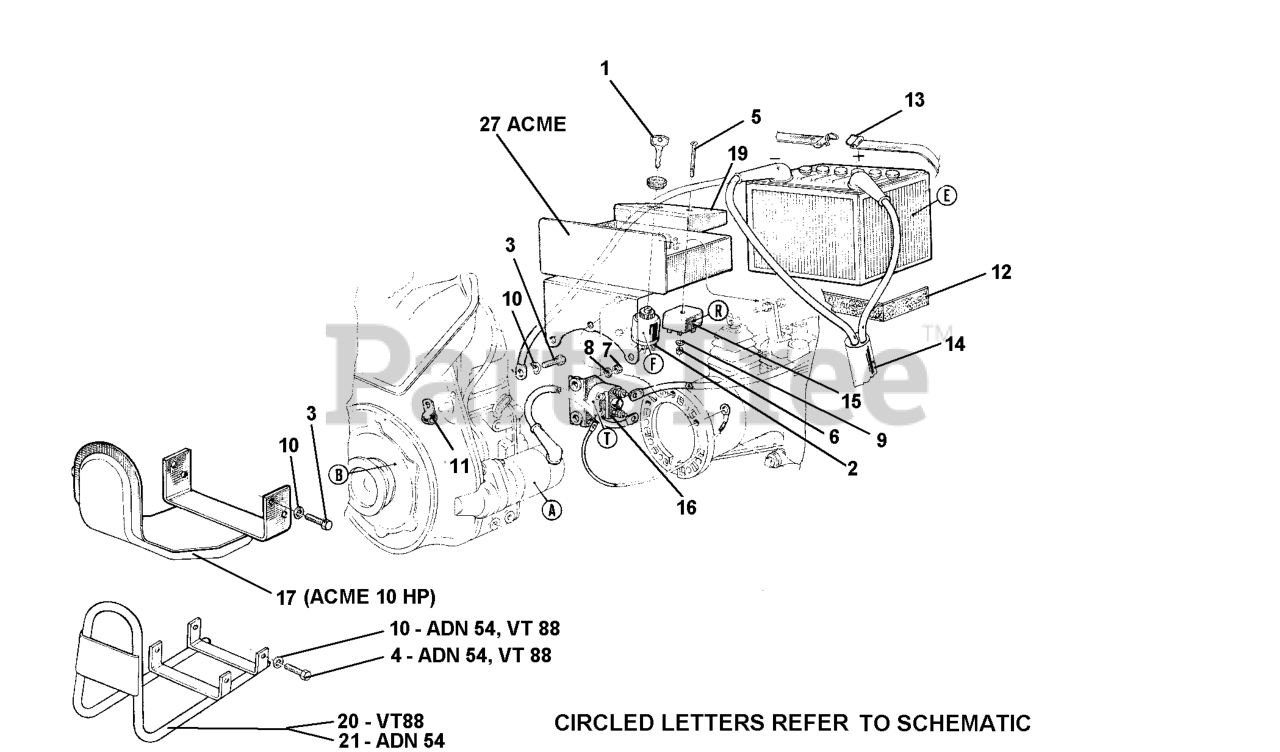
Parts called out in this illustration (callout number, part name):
3	SCREW M8 X 16
4	SCREW M8 X 20
5	SCREW TC M4 X 30 UNI 6107
8	WASHER, FLAT 6.4
9	LOCK WASHER B 4.3
10	WASHER, LOCK 8.4
11	SUPPORT, ACCELERATOR CABLE
12	SHOCK-PROOF RUBBER
13	BATTERY STRAP
14	ELEC. START CABLES MC 715
16	CHOKE DECAL
17	BOSCH RELAY 0332002160
18	GUARD, MOWER MOTOR PULLEY
19	BATTERY SUPPORT 10HP ACME
20	SUPPORT BATTERY
21	PULLEY GUARD
